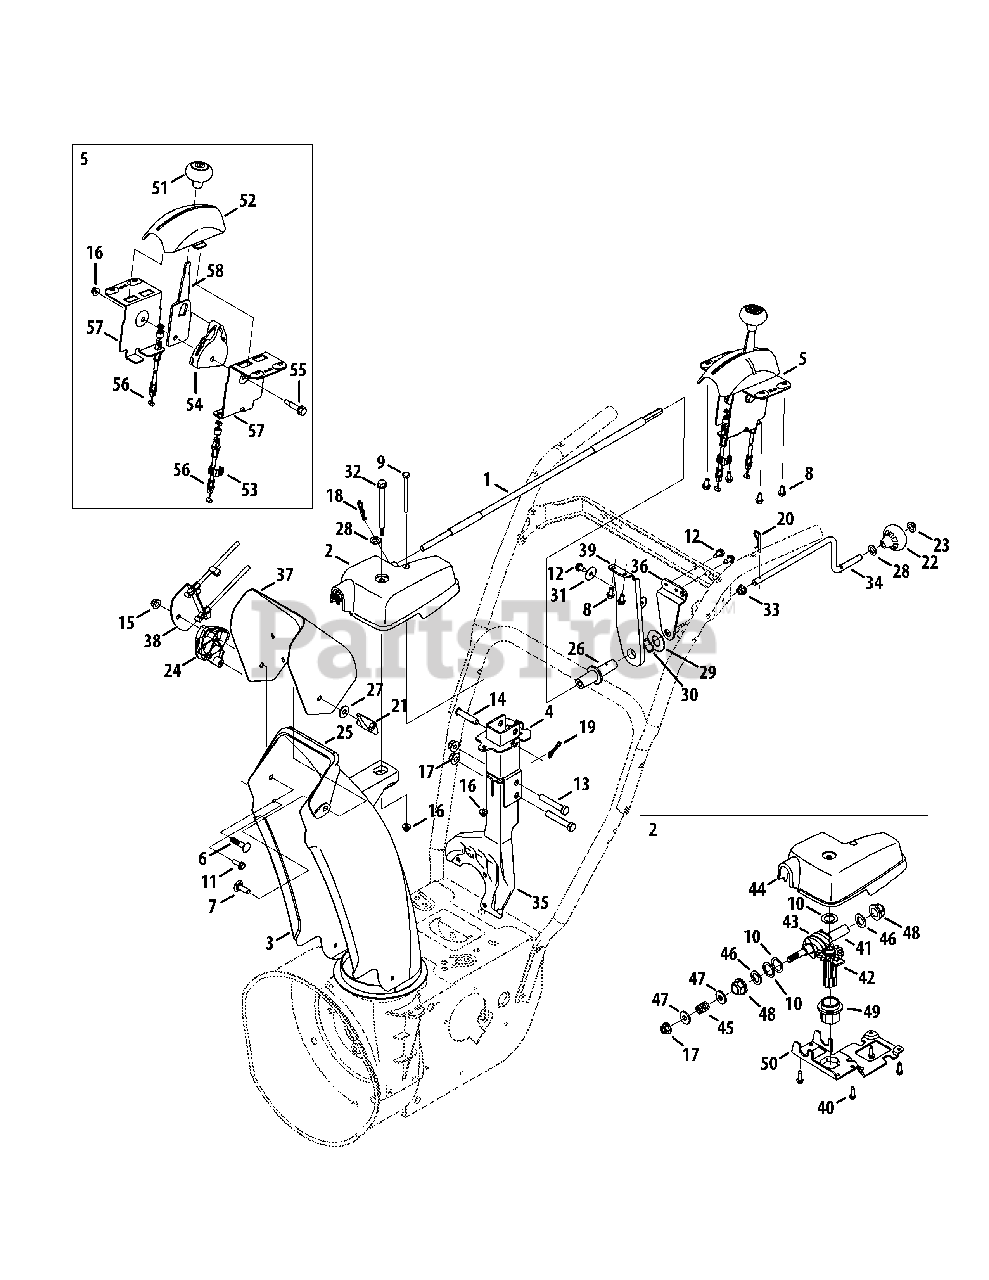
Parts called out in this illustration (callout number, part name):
1	Control Assembly
2	Chute Rotation Gearbox
4	Support Bracket Extension
5	Chute Control, 2-Way
6	Bolt, Carriage, 5/16-18 x 1.50
7	Bolt, Carriage, 5/16-18 x 1.00
8	Screw, HL, 1/4-15 x 0.50
9	Hex Head Screw, 1/4-20 x 3.00
10	Shim Washer, .632 x 1.00 x .010
11	Screw, HL, 1/4-15 x 0.750
12	Hex Washer Screw, 1/4-20 x .625
13	Hex Cap Screw, 3/8-16 x 2.25
14	Clevis Pin, 3/8 x 1.87
15	Nut, Flangelock, 5/16-18
16	Nut, Flangelock, 1/4-20
17	Flange Lock Nut, 3/8-16
18	Internal Cotter Pin
19	Bow-Tie Cotter Pin
20	Internal Cotter Pin
21	Wing Knob, 5/16-18
23	Push Cap, 3/8
24	Chute Cable Guide
25	Chute Adapter
26	Chute Control Rod Coupling
27	Washer, Flat, .349 x .879
28	Flat Washer, .375 x .738 x .063
29	Flat Washer, .78 x 1.59 x .06
30	Washer, Wave, .785 x 1.0 x .012
31	Flat Washer, .265 x 1.00 x .030
32	Screw, Shoulder, .312 x 3.5 x 1/4-20
33	Plastic Bushing, .38
35	Chute Support Bracket
36	Support Rod Bracket
38	Cable bracket
39	Chute Control Support Bracket
40	Screw, 12-16 x .75
42	Gear Assembly
43	Worm
45	Compression Spring, .39 x .60 x .88
46	Flat Washer, .625 x 1.0 x .067
47	Flat Washer, .380 x .93 x .110
48	Hex Bearing
49	Flange Bearing
51	Shift Knob
52	Cover, Tilt Cover
53	Cable Clip
54	Chute Tilt Cable Guide
55	Screw, Shoulder, .31 x .995:1/4-20
56	Cable, Chute Tilt
57	Bracket, Mounting
